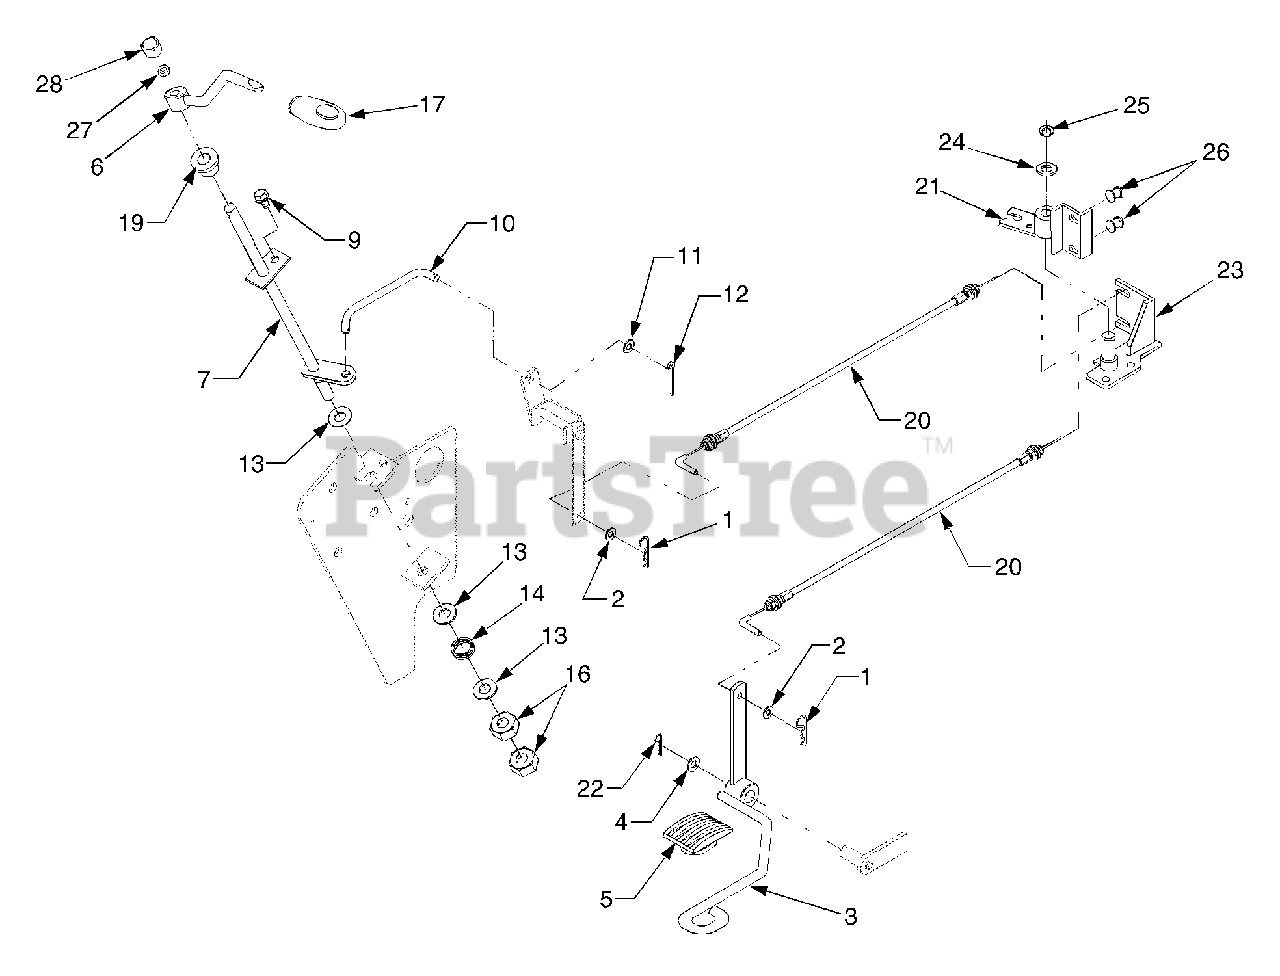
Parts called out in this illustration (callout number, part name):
2	Washer, Plain
4	Washer, Plain
5	Rubber, Accel Pedal
6	Lever 1, Hand Accel
7	Lever 2, Hand Accel
10	Rod, Connector
11	Washer, Plain
13	Washer, Plain
17	Grip (Hand Accel)
20	Cable, Accelerator
23	Bracket, Accel
24	Washer, Plain
